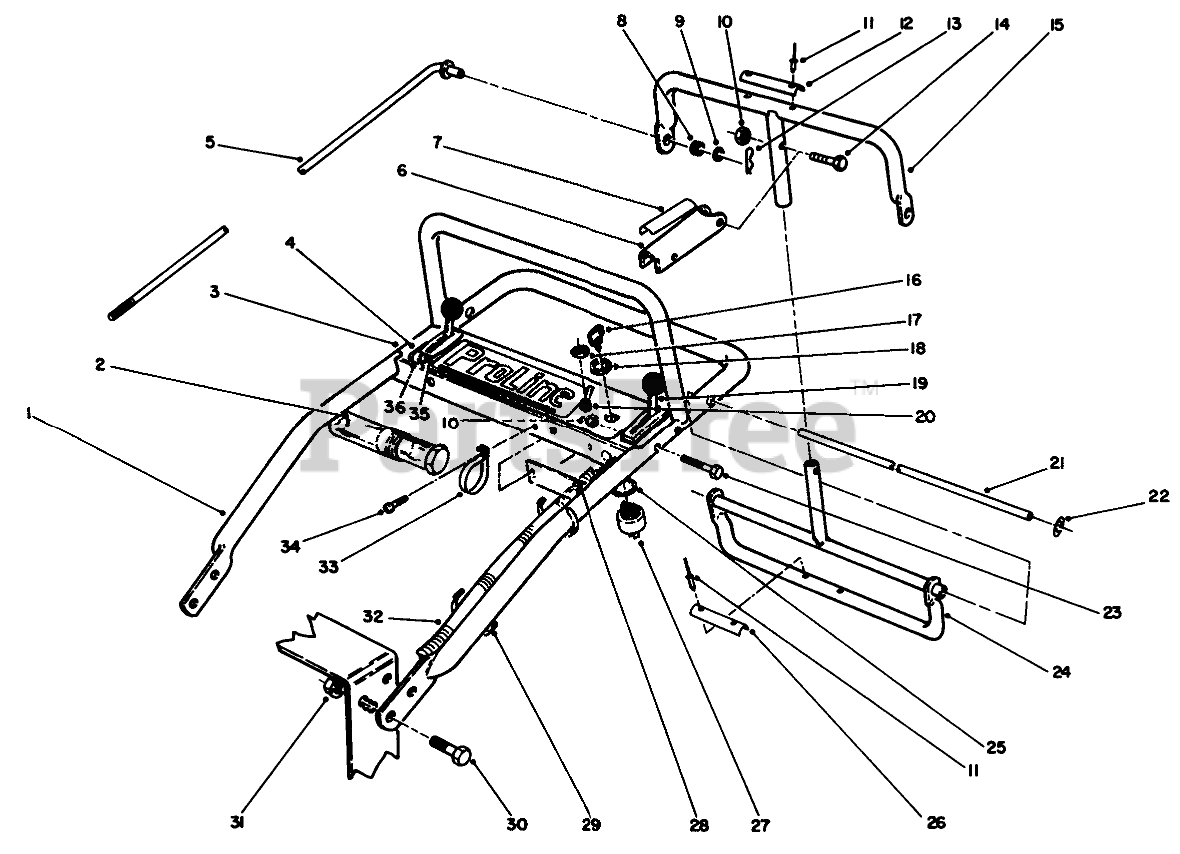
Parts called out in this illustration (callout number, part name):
1	Handle-Upper
2	TUBE-MANUAL
3	CONTROL PANEL B
4	Decal-Proline
5	CONTROL ROD B
6	Lever-Parking Brake
7	DECAL-LEVER, PARKING
8	GROMMET-RUBBER
9	WASHER-FLAT
10	NUT-LOCK, NI
11	RIVET-BLIND
12	DECAL-CONTROL BAR
13	PIN-COTTER
14	SCREW-SHH
15	Bar-Control
16	KEY-IGNITION
17	NUT
18	NUT-HH
19	THROTTLE CONTROL
20	Switch-Clutch (Incl. Ref. #17)
21	PIVOT ROD
22	NUT-PUSH-ON, CIRCULAR
23	SCREW-SHH
24	Control Pivot
25	WASHER-TOOTH, INTERNAL
26	DECAL-REVERSE HANDLE
27	Switch-ignition (Incl. Ref. #16, 18, & 25)
28	PANEL-BOTTOM
29	TIE-CABLE
30	SCREW-HHF
31	NUT-HF
32	16 HP WIRING HARNESS
33	CLAMP-R
34	SCREW-HWHTF
35	CHOKE CONTROL
36	SPACER
